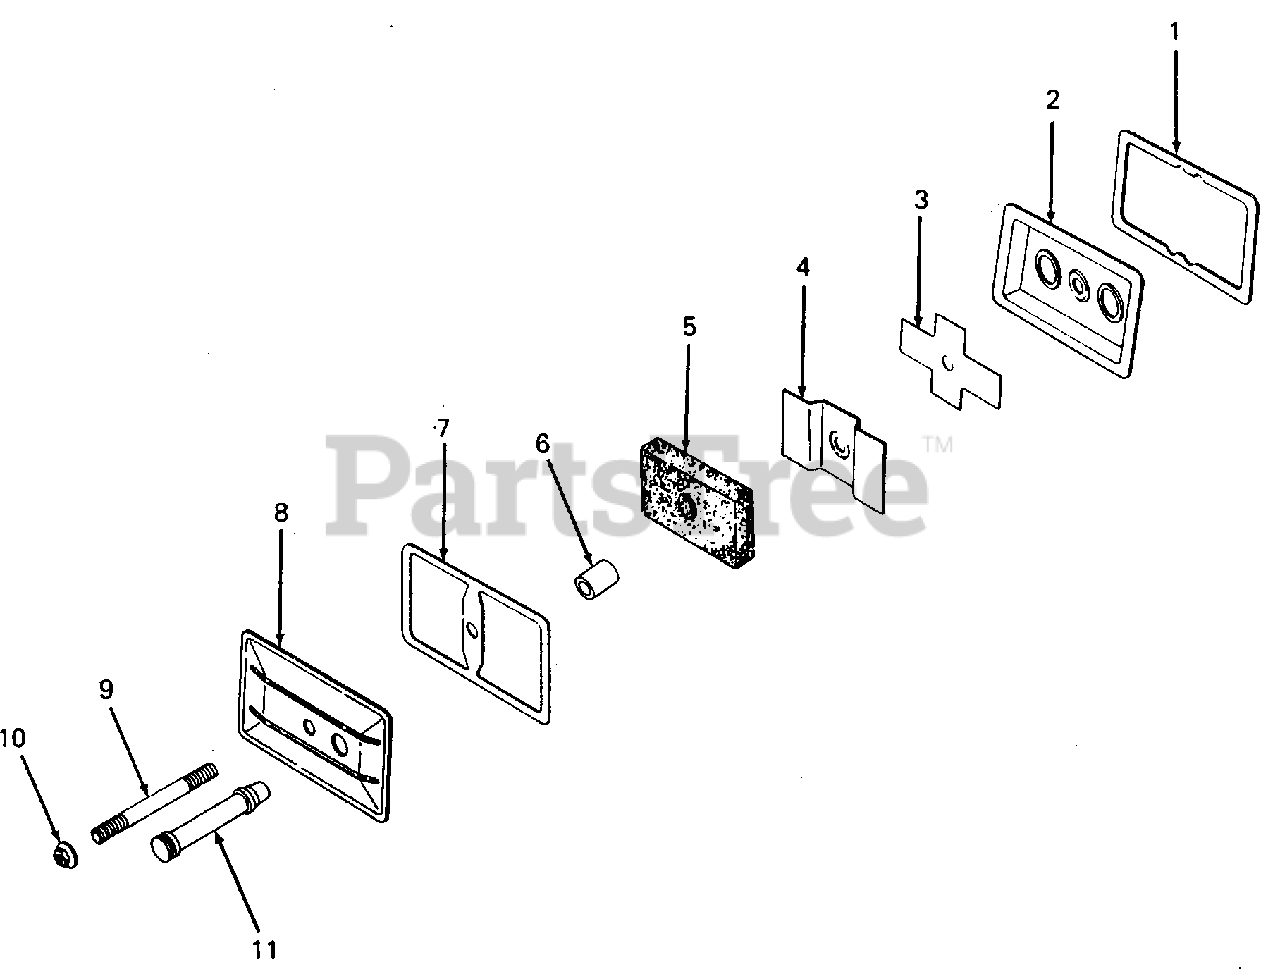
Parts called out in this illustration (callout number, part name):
1	Gasket, Breather Plate
2	Plate, Breather
3	Reed, Breather
4	Baffle, Breather
5	Filter, Breather
6	Seal, Breather
7	Gasket, Valve Cover
8	Cover, Valve
9	Stud, 1/4-20 X 3-1/4
10	Palnut, 1/4-20
11	Hose, Breather
